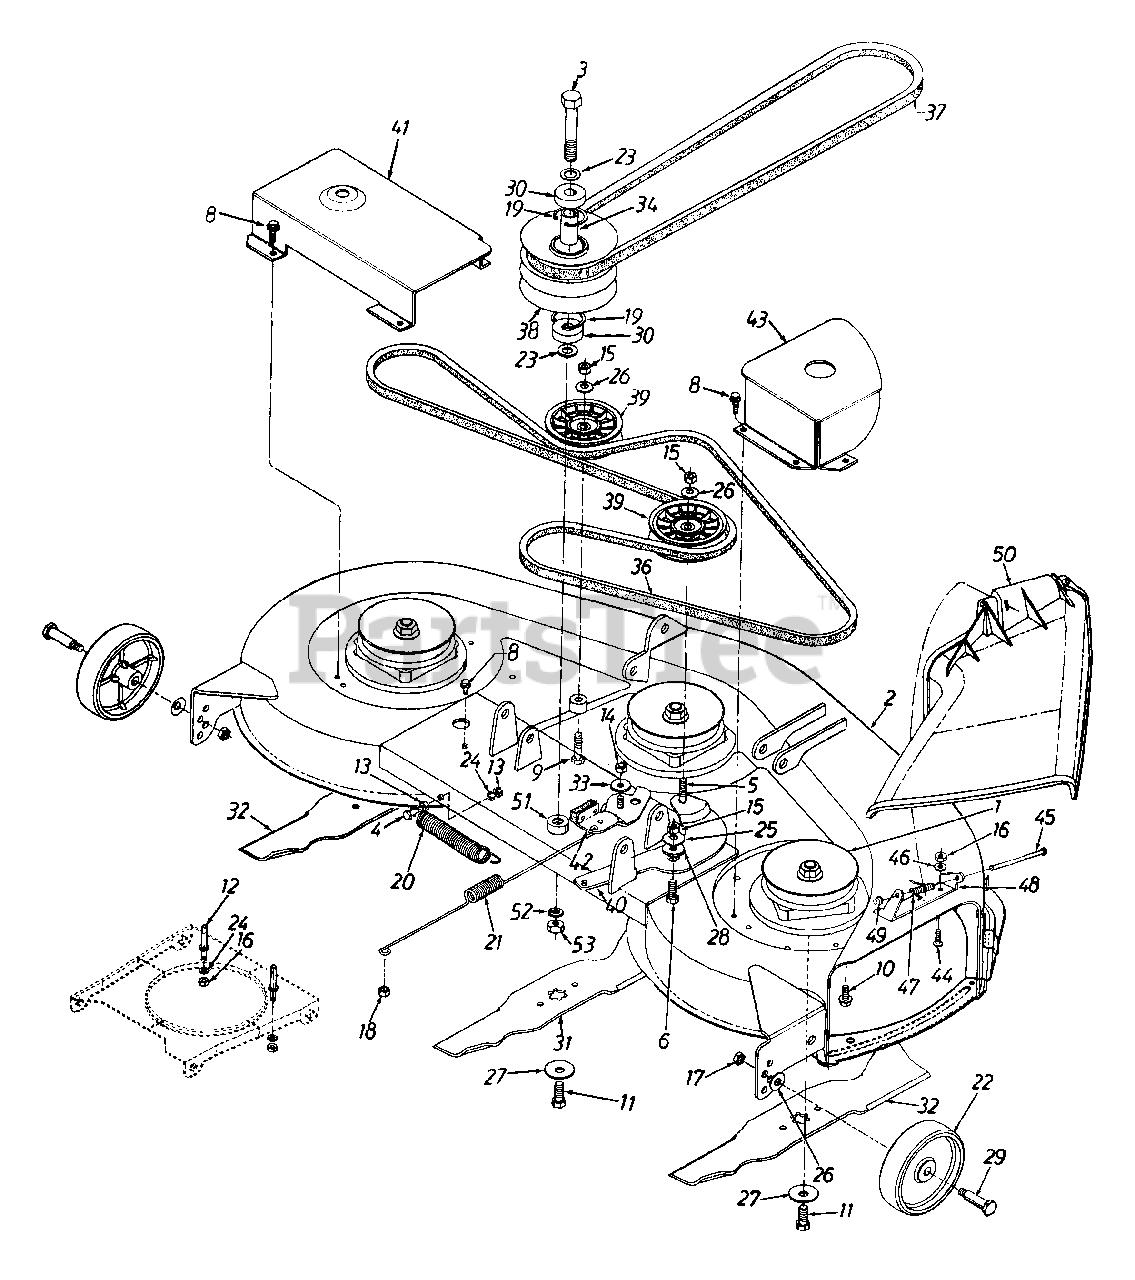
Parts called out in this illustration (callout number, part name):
1	Blade Spindle Ass'y.
4	Hex Bolt 1/4-28 x 1.25" Lg.
5	Hex Bolt 3/8-24 x 1.5" Lg.
6	Hex Bolt 3/8-24 x 1" Lg.
8	Hex Wash. Hd. TT-Tap Scr. 1/4-20 x .5" Lg.
9	Hex Bolt 3/8-24 x 2" Lg.
10	Hex Flange Bolt 5/16-24 x .75" Lg.
11	Hex Patch L-Bolt 7/16-20 x 1" Lg.
12	Belt Guard Pin
13	Hex Nut 1/4-28 Thd.
14	Hex Ins. L-Nut 5/16-24 Thd.
15	Hex Nut 3/8-24 Thd.
16	Hex Nut 1/4-20 Thd.
17	Hex Top Jam Nut 3/8-16 Thd.
18	Hex Patch L-Nut 5/16-18 Thd.
19	Int. Snap Ring
20	Ext. Spring .88" O.D. x 6.17"
21	Ext. Spring .788" O.D. x 15.5"
22	Deck Wheel
23	Fl-Wash. .635" I.D. x 1" O.D. x .06"
24	L-Wash. 1/4" I.D.
25	Bell-Wash. 3/8" x 1.125" x .062"
26	Bell-Wash. 3/8" x .87" x .064"
28	Shoulder Spacer .625" I.D. x .169"
29	Shld. Bolt .498" x 1.525"
30	Ball Brg. .625" I.D. x 1.574" O.D. x .47"
31	High Lift Blade 14.88" Lg.
32	High Lift Blade 16.28" Lg.
33	Shoulder Spacer
34	Spacer .635" I.D. x .088" O.D.
36	V-Belt
37	V-Belt
38	Pulley Double Deck 5" O.D.
39	Flat Idler Pulley 3.5 O.D.
42	Deck Brake Brkt. Ass'y.
44	Hex Bolt 1/4-20 x .62" Lg.
45	Hinge Pin
46	Bell-Wash. 1/4" I.D.
47	Torsion Spring
48	Hinge Mtg. Brkt.
50	Chute Ass'y. Comp.
51	Spacer .635" I.D. x 1" O.D.
52	L-Wash. 5/8" I.D.
53	Hex Nut 5/8-18 Thd.
